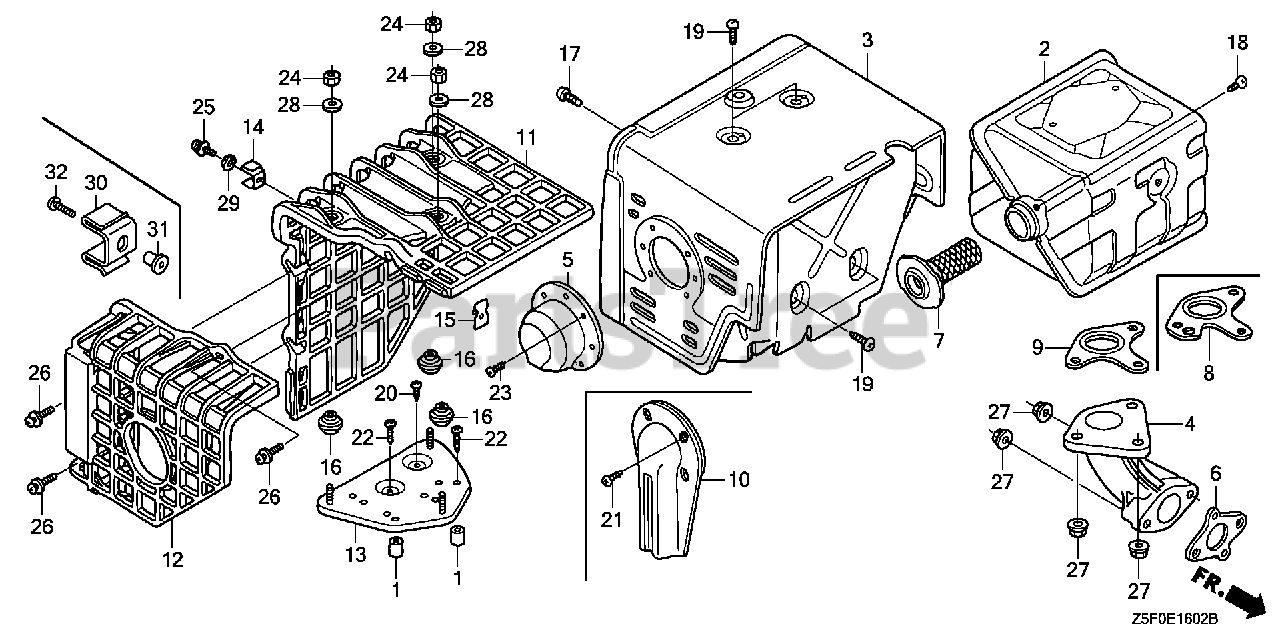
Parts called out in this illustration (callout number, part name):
1	COLLAR, AIR CLEANER HOUSING
2	MUFFLER (100DB)
3	PROTECTOR, MUFFLER
6	GASKET, EX. PIPE
7	ARRESTER, SPARK
8	GASKET, MUFFLER (ARRESTER) (NIPPON LEAKLESS)
9	GASKET, MUFFLER (NIPPON LEAKLESS)
10	DEFLECTOR, MUFFLER
11	COVER, MUFFLER
12	COVER, RR. MUFFLER
13	BASE, MUFFLER COVER
14	STAY, MUFFLER COVER
15	PLATE, SET
16	SPACER, MUFFLER COVER
17	SCREW, TAPPING (6X10)
18	SCREW, TAPPING (4X6)
19	SCREW, TAPPING (5X8)
20	SCREW, TAPPING (5X8)
21	SCREW, TAPPING (4X6)
22	SCREW, TAPPING (5X25)
24	NUT, HEX. (5MM)
25	SCREW-WASHER (5X12)
26	SCREW-WASHER (6X20)
27	NUT, FLANGE (8MM)
28	WASHER, PLAIN (5MM)
29	WASHER, SPRING (5MM)
